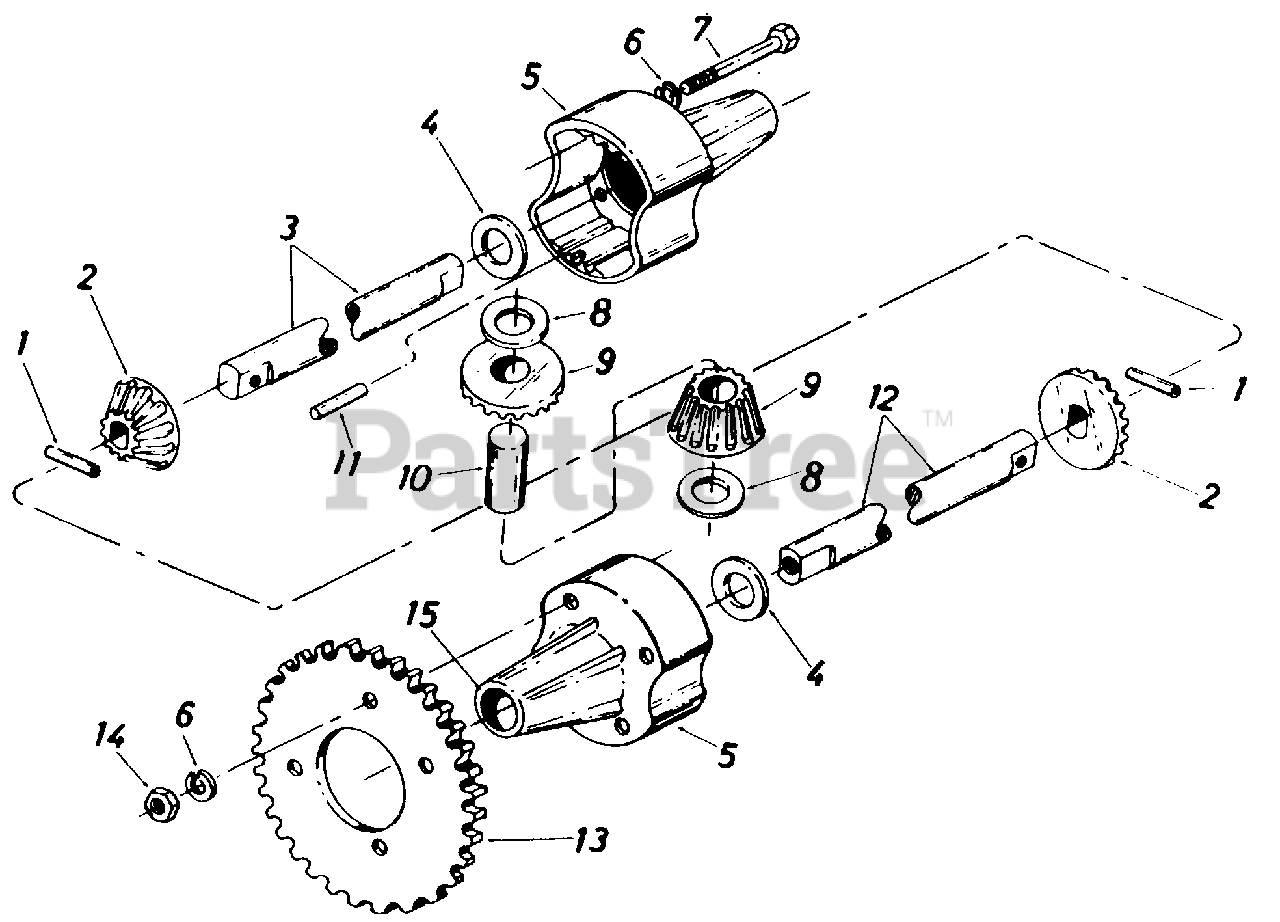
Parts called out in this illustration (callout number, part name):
1	Spring Pin Spiral 3/16 Dia. x 1.00" Lg.
2	Gear-Double"D" Hole
3	Shaft (Long) -15.11 " Lg.
4	Fl-Wash. .760 I.D. x 1.49 O.D.
5	Housing Half
6	L-Wash. 5/16" I.D.
7	Hex Bolt 5/16-24 x 4.00" Lg.
8	Fl-Wash. .640 I.D. x .24 O.D.
9	Gear-Round Hole
10	Drive Pin
11	Dowel Pin 3/16" Dia. x .62" Lg.
12	Shaft (Short) 7.58" Lg.
13	Sprocket-48 Teeth
14	Hex Cent. L-Nut 5/16-24 Thd.
15	Flange Bearing
